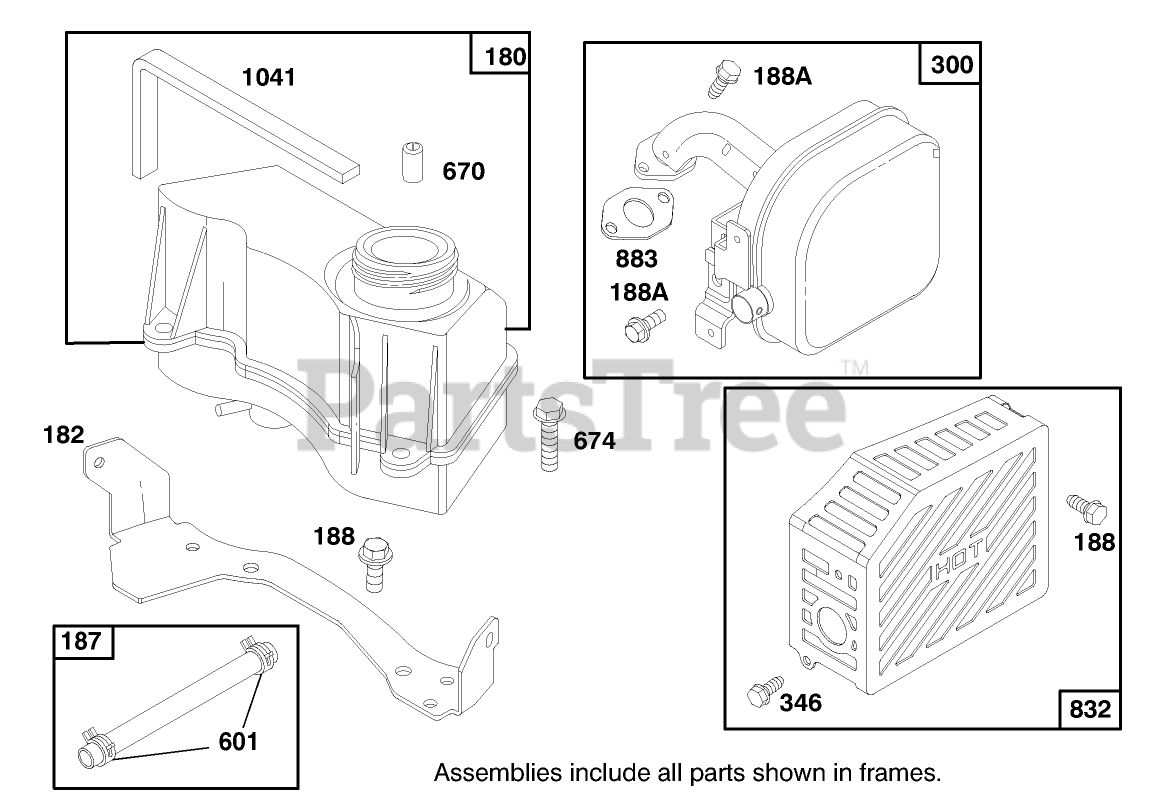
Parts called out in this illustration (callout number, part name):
187	BRIGGS 296004
188A	SCREW - HEX HEAD
300	MUFFLER - EXHAUST
346	SCREW - SELF-TAPPING
670	SPACER
674	SCREW - HEX HEAD
